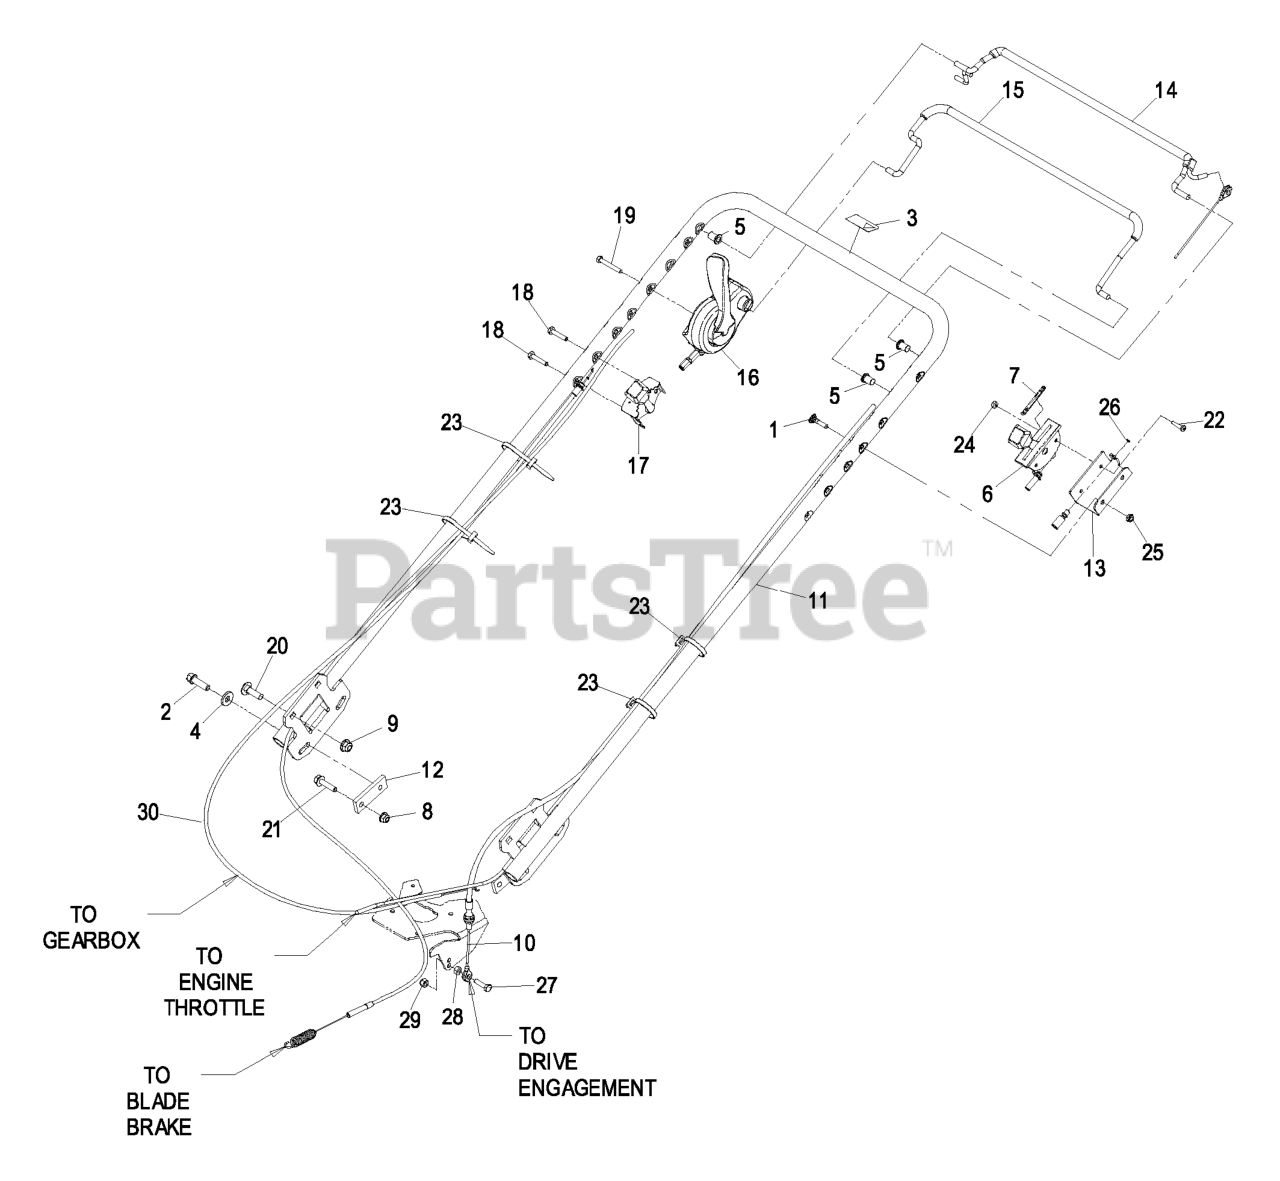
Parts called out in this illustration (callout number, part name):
1	SCREW-HANDLE
2	SCREW-TAPTITE
3	DECAL-PROTECTION, EAR
4	WASHER-BELLEVILLE
5	BUSHING
6	CONTROL-THROTTLE
7	DECAL-THROTTLE / CHOKE
8	NUT-HF, NI
9	NUT-HF, NI
10	CABLE-TRACTION
11	ASM,HANDLE W/DECALS
12	NUT-HANDLE
13	BRACKET-CONTROL
15	BAIL-BBC (WITH GRIP)
16	CONTROL-BBC
17	CONTROL-SHIFT
18	SCREW-HH
19	SCREW-HH
20	BOLT-CARR
21	SCREW-HHF
22	SCREW-PPH
23	TIE-CABLE
24	NUT-LOCK, NI
25	NUT-LOCK, NI
27	SCREW-HH
28	NUT-HEX
29	NUT-LOCK, NI
30	CABLE-SHIFTER
